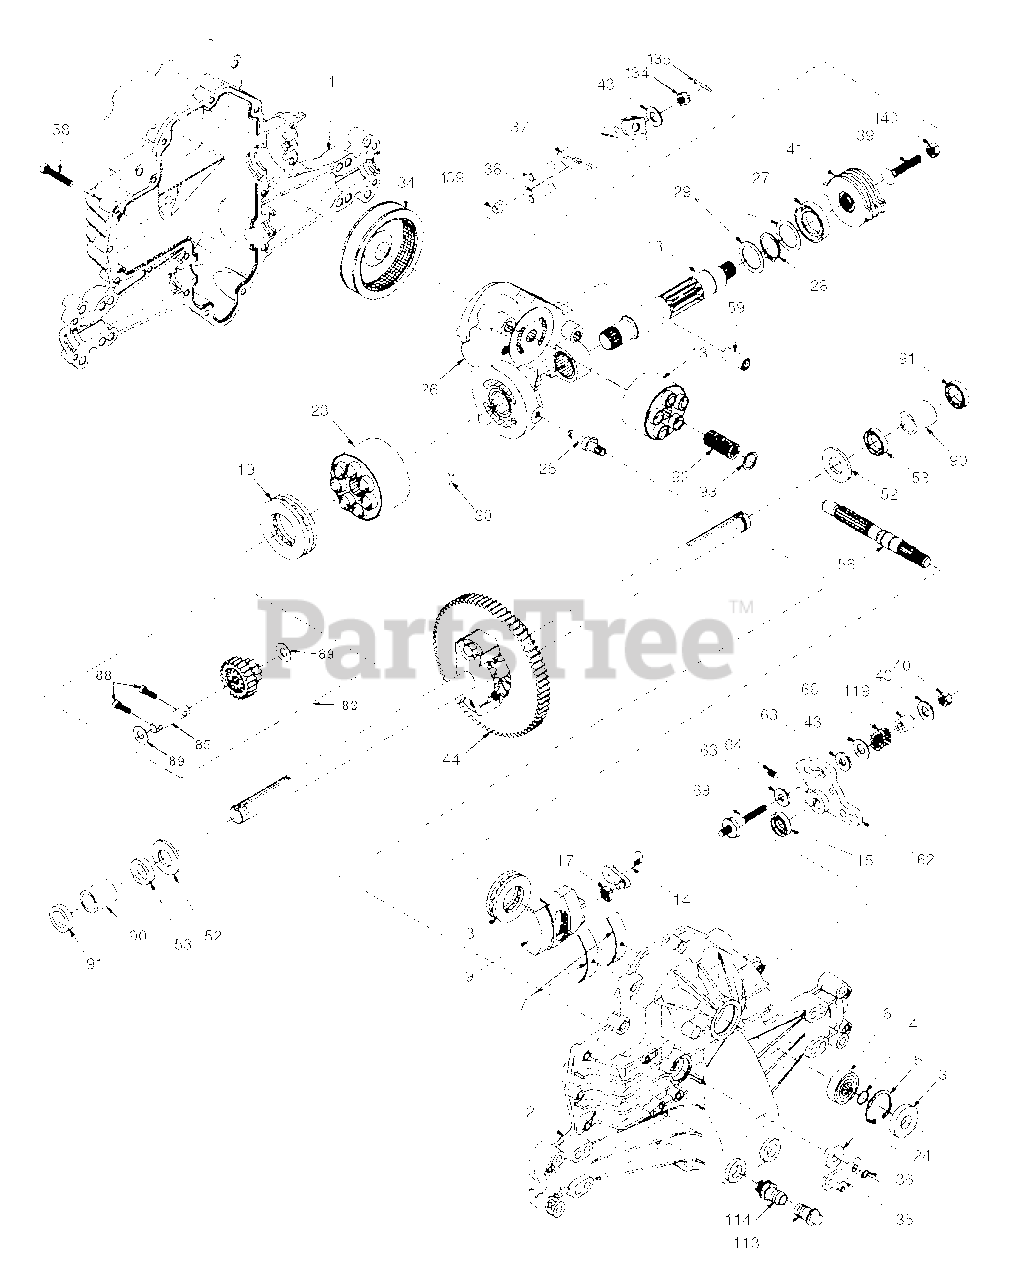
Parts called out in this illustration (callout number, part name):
1	Housing, Lower
2	Assembly, Upper Housing
3	Seal, Lip
4	Ring, Wire Retaining
5	Ring, Retaining
6	Bearing, Shaft Ball
7	Bearing, Cradle
8	Bearing, Thrust 30 x 52 x 13
9	Swashplate, Variable
13	Block, Cylinder Assembly
14	Arm, Trunnion
15	Seal, Lip
17	Guide, Slot
18	Shaft, Motor
19	Bearing, Thrust 42 x 68 x 16
23	Block, Cylinder Assembly
24	Seal, Lip 10 x 25 x 7
25	Actuator, Bypass
26	Center Section Assembly Kit
27	Seal, Lip 26 x 42 x 8
28	Ring, Retaining
29	Washer 26 x 35 x 1
30	Plate, Bypass
34	Oil Filter Element
35	Arm, Bypass
36	Ring, Retaining
37	Arm, Actuating
38	Pin, Actuating
39	Bolt 5/16-24 x 1-3/4
40	Locknut, Hex 5/16-24 UNJC
41	Brake Rotor/Stator Kit
43	Washer 7/16 x 7/8 x .060
44	Differential Assembly
52	Washer 3/4 x 1.5 x .13
53	Seal .75 x 1.25 x .250
56	Shaft, Input
58	Bolt 1/4-20 x 1.38
59	Pin .5 OD x .43 ID x .750
62	Arm, Control
63	Puck, Dampener
64	Set Screw
68	Spring
69	Stud 5/16-24
83	Jackshaft Assembly
85	Jackshaft
88	Screw, Cap
89	Washer 7/16 x 1 x 1/2
90	Sleeve Bearing
91	Seal, Wiper
92	Spring, Block
93	Washer, Block Thrust
113	Cap, Vent Assembly
114	Fitting, O-Ring Assembly
119	Spacer
134	Nut, Castle 5/16-24
135	Pin, Cotter
139	Spring, Compression
140	Nut, Hex 5/16-24
